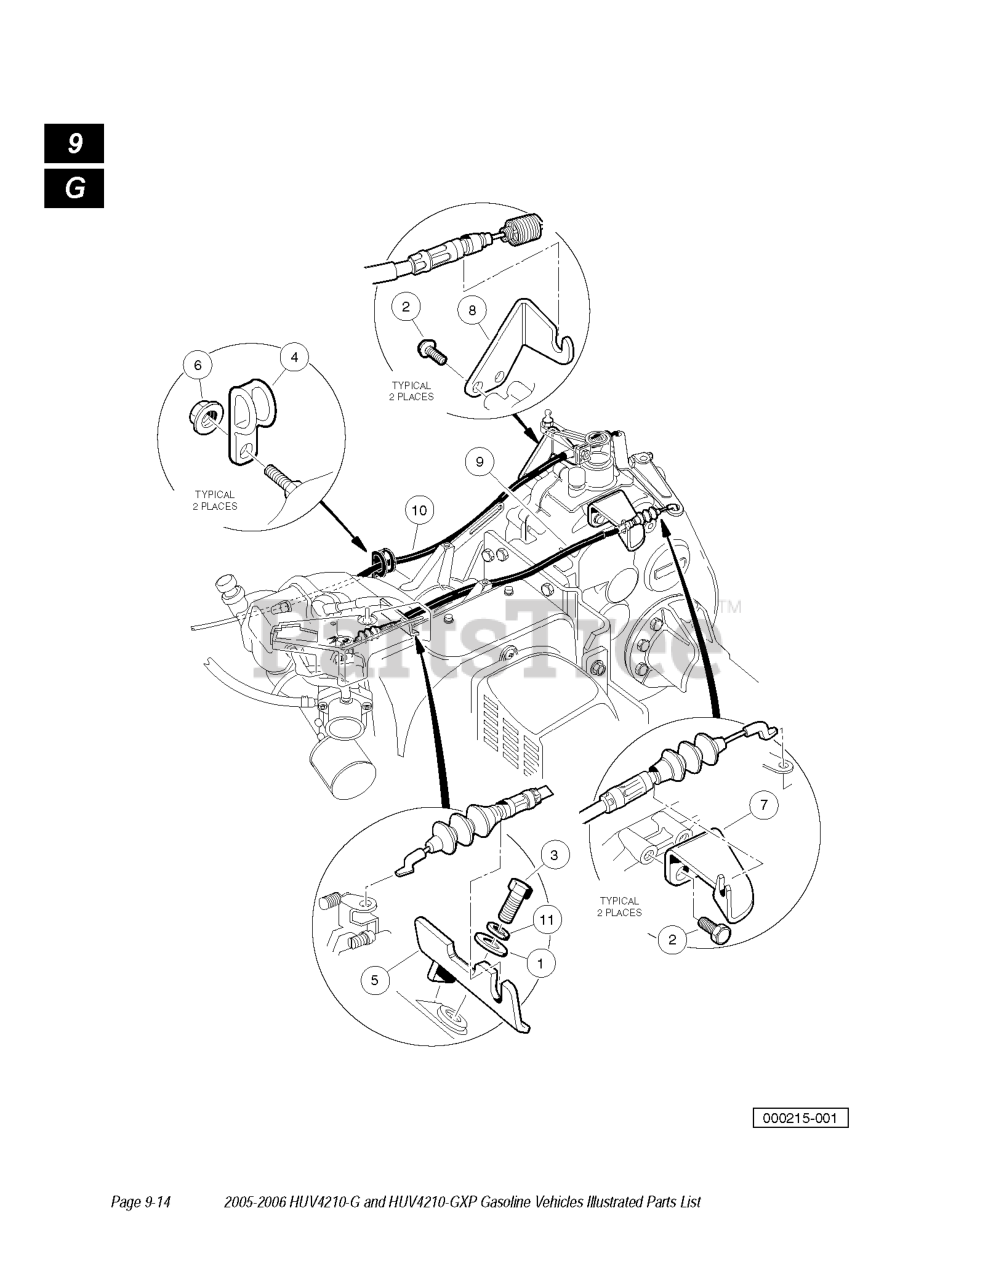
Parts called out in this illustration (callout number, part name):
1	WASHER, 5/16 FLAT
2	SCREW HX TYP TT
3	SCREW, M8-125 X 22 HEX GR.8.8
5	BRACKET, GOVERNOR CABLE ENGINE
7	BRKT, REAR GOV CABLE SNAP-IN
8	BRKT, REAR ACC CABLE SNAP-IN
9	CABLE, GOV, SNAP-IN
10	CABLE, ACC, SNAP-IN
11	LOCKWASHER, 5/16 SPLIT
